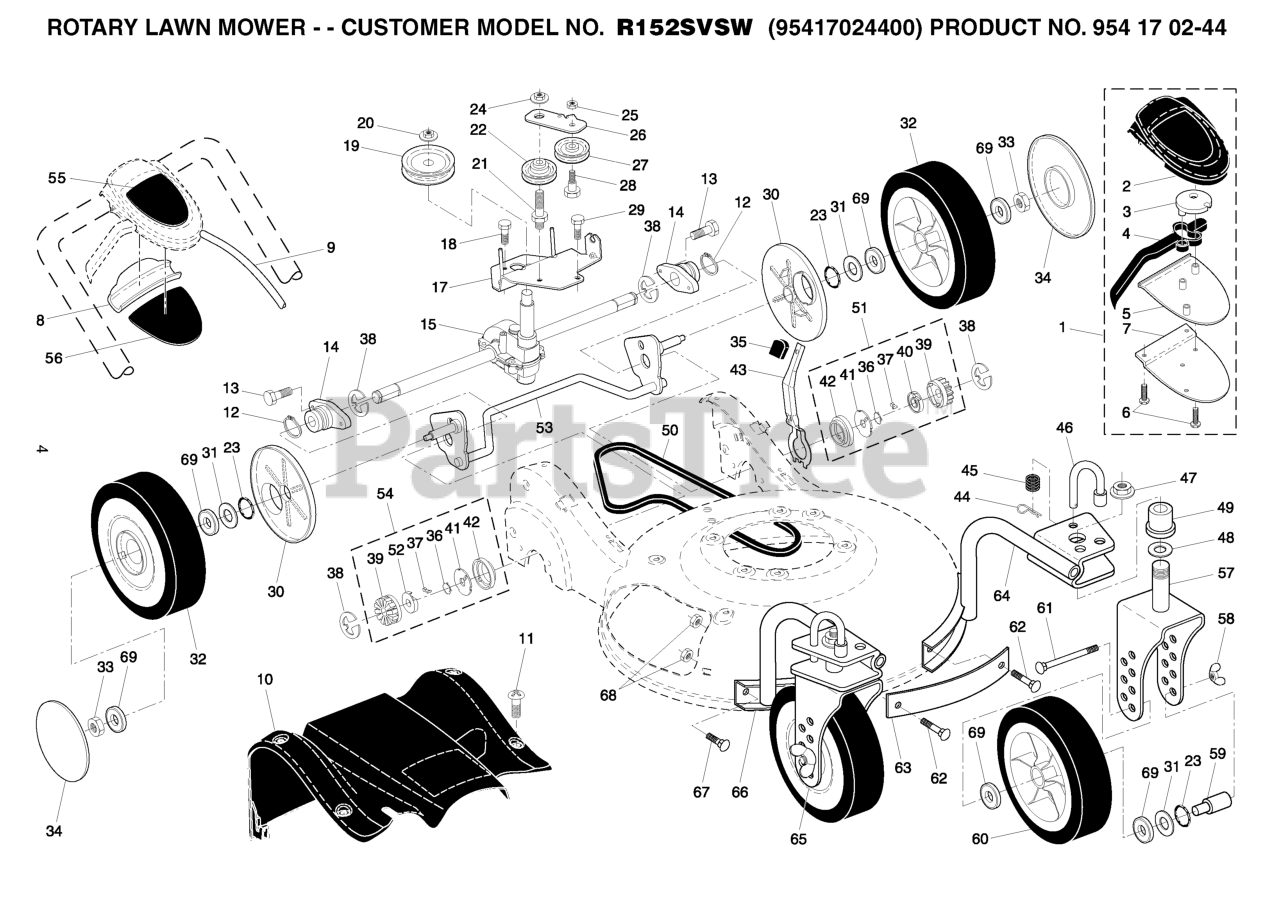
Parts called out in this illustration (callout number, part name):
1	EZ WALK CONTROL
2	COVER, DRIVE CONTROL, TOP
3	PULLEY.CAM.DRIVE.CONTROL.HV
4	LEVER
5	COVER, DRIVE CONTROL BOTTOM
6	SCREW, PHILLIPS HEAD 10 X 5/8
7	BRACKET, DRIVE CONTROL
8	EZ WALK SNAP COVER PLATE
10	COVER ASM. DRIVE
11	SCREW
12	RETAINING RING (2 2)(3 2)
13	RP SCREW
14	BEARING.SUPPORT.ASSEM
15	TRANSMISSION.ASM.RGD.EZ.21
16	BEARING.8".WHEEL
17	BRACKET, TRANSMISSION
18	Screw, Hex Washer Head #10-24 x .668
19	RP PULLEY DRIVE
20	FLANGED LOCKNUT 3/8-16 ZINC
21	BOLT, IDLER
22	PULLEY ASSY
23	O-RING
24	NUT
25	NUT.CENTERLOCK.5/16-
26	BRACKET
27	IDLER PULLEY
28	SHOULDER BOLT
29	SCREW 14-20 X 5/8
30	DUST COVER, WHEEL
31	WASHER.FLAT.1/2
32	WHEEL.9X2.25.PR.JUNG.BLK
33	HEX FLANGE LOCKNT
34	RB HUBCAP.3-SPOKE.SILVER
35	KNOB.SELECTOR.SPRG.H-GRY (2 2)
36	SPRING, TORSION
37	PAWL.DRIVE.21.EZ-WALK
38	E-RING 7/16 RE
39	GEAR, PINION
40	RETAINER.DRIVE.21.EZ-WALK.LT
41	DISC.DRIVE.21.EZ-WALK
42	SEAL.PINION
43	LEVER, SELECTOR, HEIGHT, REAR
48	WASHER.FLAT.1/2
50	BELT.DRIVE.EZ.WALK.HI-VAC
51	PINION ASSY, LH
52	RETAINER, DRIVE, RH
53	AXLE.ASM.REAR.TORQUE.BZP
54	PINION ASSY, RH
55	DECAL, DRIVE
57	BRACKET, CASTER
58	NUT.WING.5/16-18.YELLOW
60	WHEEL.9X2.25.LP.JUNG.SILV.BB.1
61	CARRIAGE BOLT
63	STRAP, FRONT
64	SUPPORT TUBE ASSY, LH BLK
65	BRACKET CASTER WHEEL, RH
66	SUPPORT TUBE ASSY, RH
68	NUT
